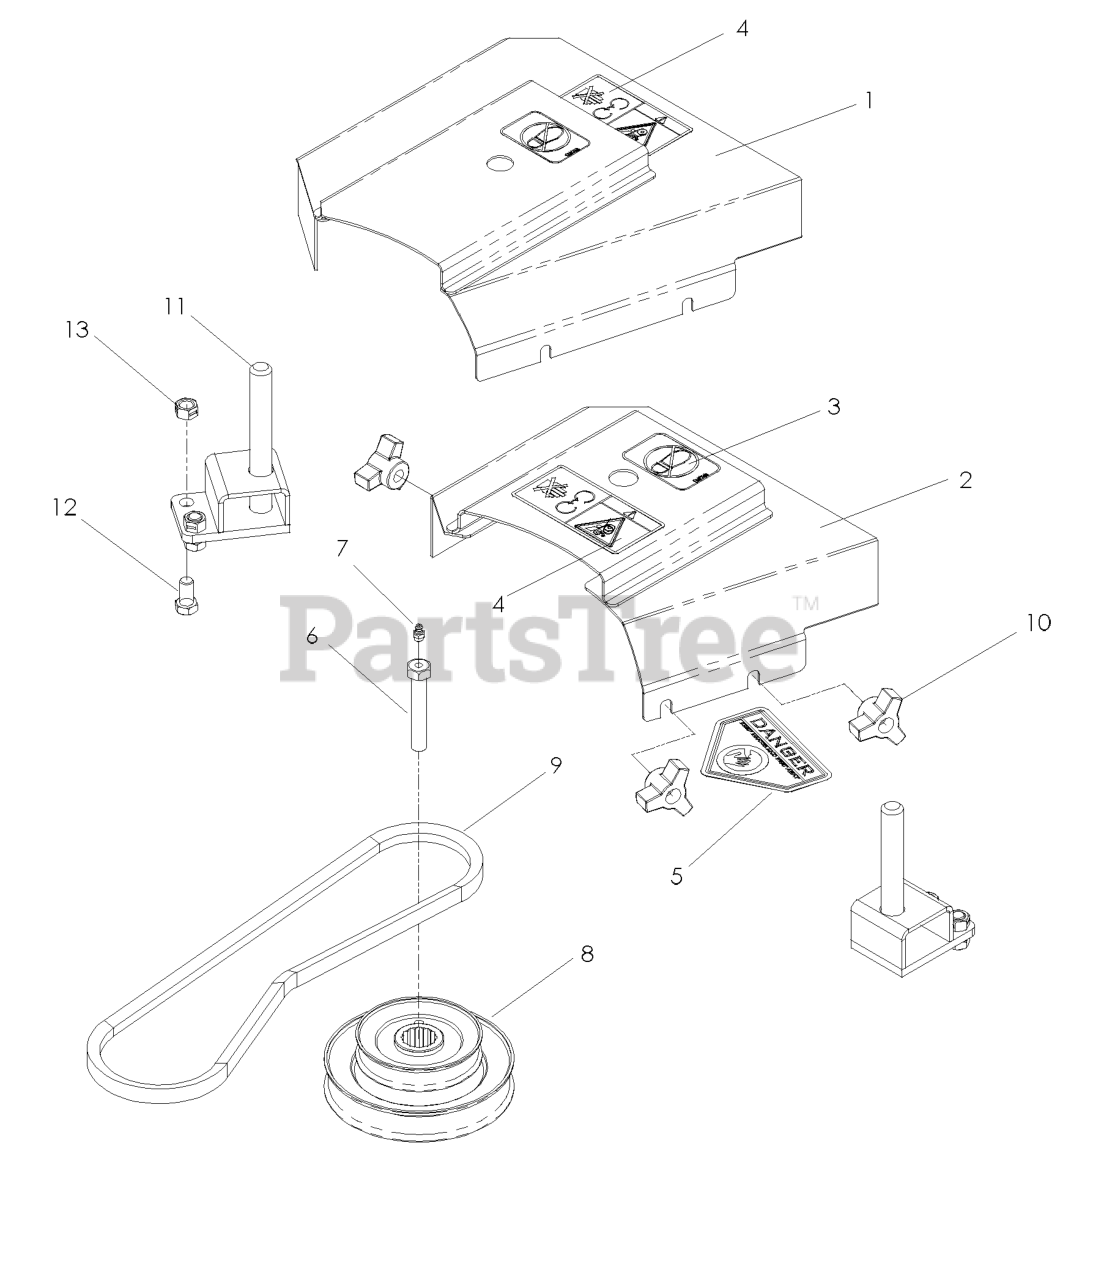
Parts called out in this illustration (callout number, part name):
1	BELT SHIELD W/DECALS, 52
2	BELT SHIELD W/DECALS, 61
3	DECAL, NO STEP
4	DECAL, BELT DRIVE
5	DECAL, CPSC
6	HCS, 7/16-20 X 2 1/2, GR8
7	ZERK
8	61 DBL HEX HEAD STACKED PULLEY
9	V-BELT PUMP DRIVE
9	V-BELT 61" SPINDLE DRIVE
10	KNOB, THREE PRONG
11	BLOWER PIN WELDMENT ASM.
12	SCREW 3/8C X 3/4 HEX CAP
13	NUT 3/8C CENTERBLOCK
